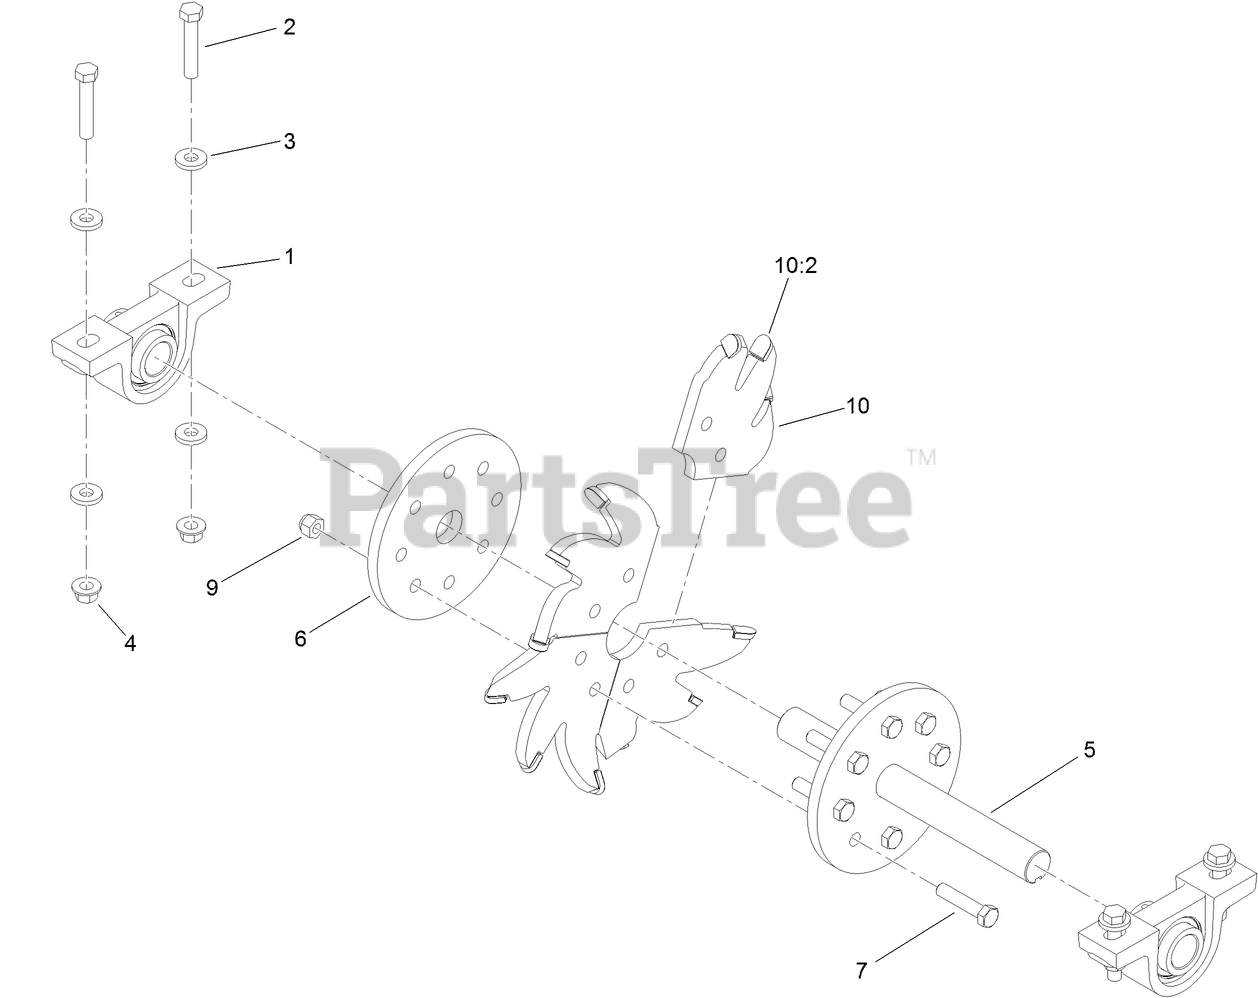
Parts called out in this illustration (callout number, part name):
1	BEARING ASM
2	SCREW-HH
3	SPACER
4	NUT-LOCK
5	BLADE SHAFT ASM
6	FLANGE-SHAFT
7	SCREW-HH
9	NUT-LOCK, NI
10	BLADE-GRINDER
10:2	TIP-CARBIDE
